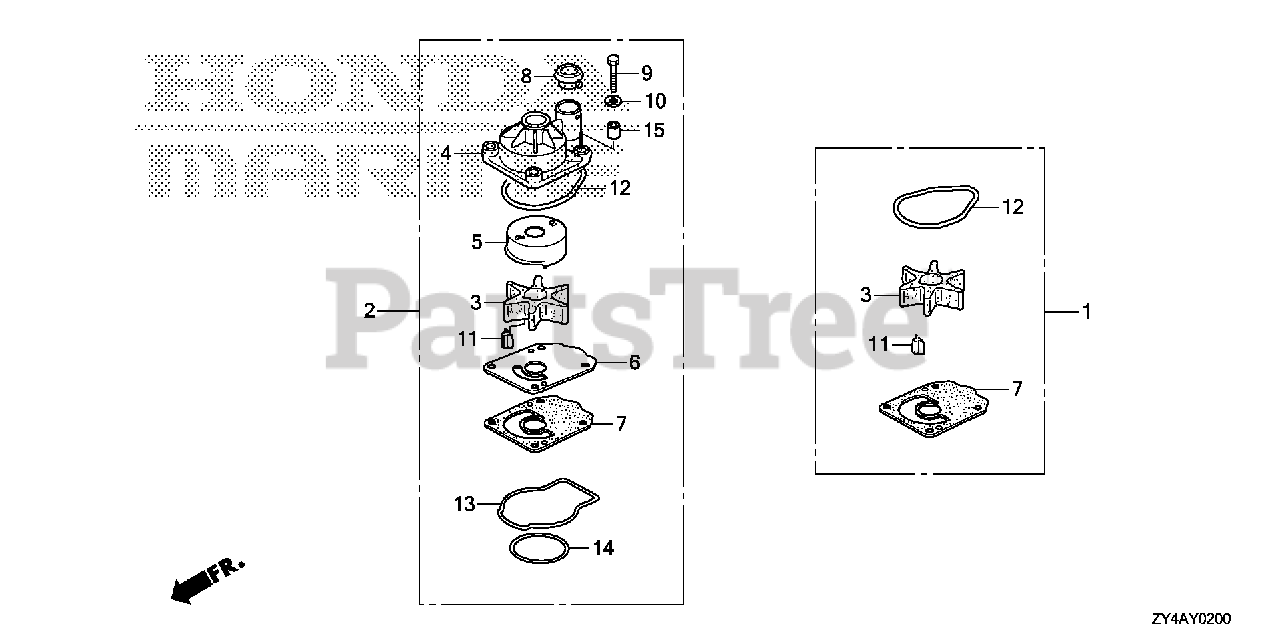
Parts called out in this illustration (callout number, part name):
1	PUMP KIT, IMPELLER
2	PUMP KIT, IMPELLER
3	IMPELLER, PUMP
4	HOUSING, IMPELLER
5	LINER, PUMP
6	COVER, IMPELLER
7	GASKET B, IMPELLER
8	RING, WATER TUBE SEAL
9	BOLT, HEX. (8X60)
10	WASHER (8MM)
11	KEY, WOODRUFF
12	O-RING, WATER PUMP
13	O-RING, WATER PUMP HOUSING
14	O-RING (69.1X2.4)
15	COLLAR, DISTANCE
